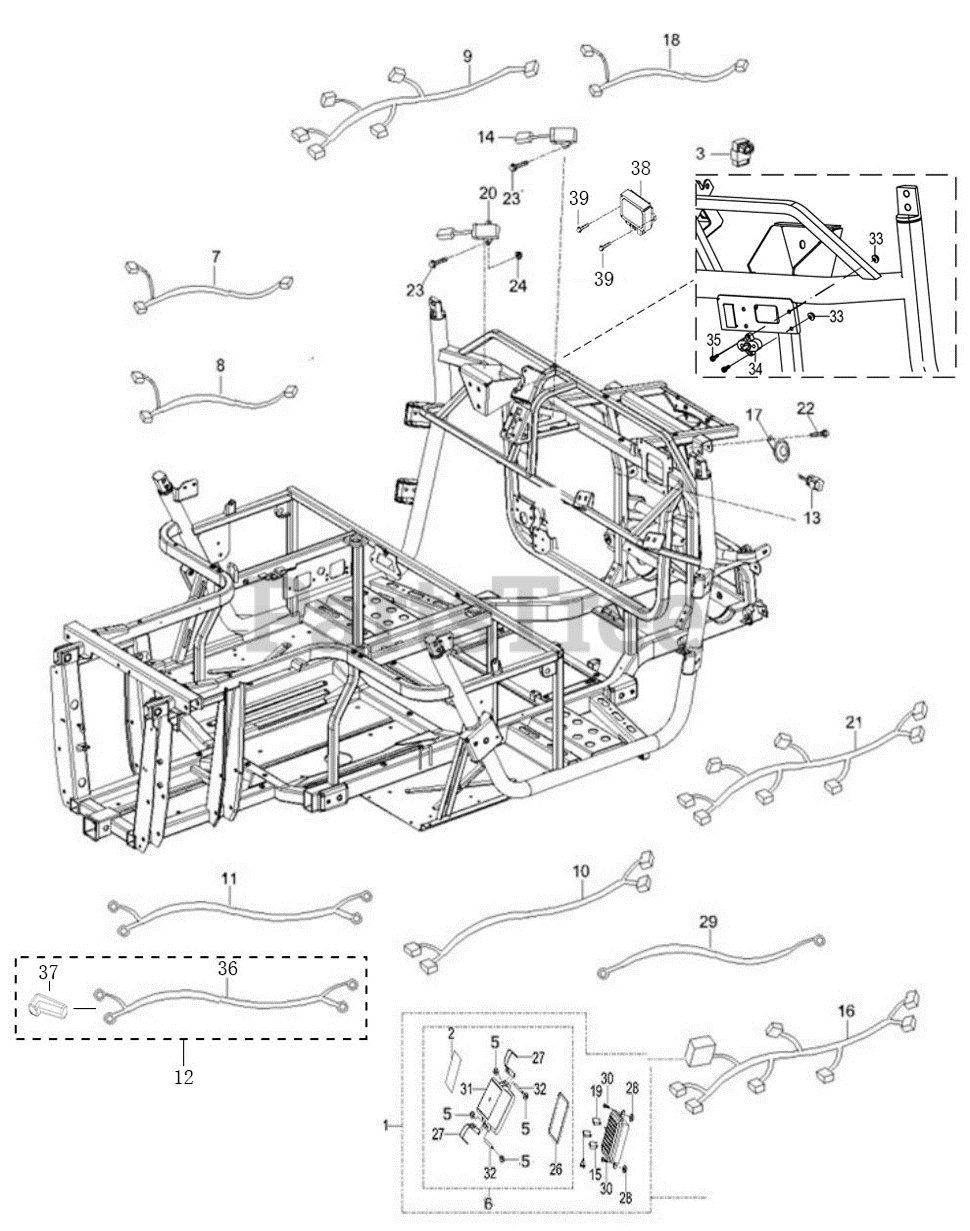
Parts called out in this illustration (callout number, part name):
1	Fuse Box
2	FUSE BOX LABEL
3	RELAY (Rear Diff)
4	SUPPLEMENTARY RELAY
6	FUSE BOX COVER W/ GASKET
7	SWITCH HARNESS
8	CABLE-SWITCH KIT 2
9	GROUND HARNESS
10	VOLTAGE REGULATOR HARNESS
11	CABLE-WINCH RELAY OUTLET
12	WINCH CABLE
13	RADIATOR FAN RELAY
15	CUTOUT RELAY
16	MAIN HARNESS
17	HORN ASSEMBLY
18	BATTERY HARNESS
19	FLASHER RELAY
20	SPEED LIMITER 750 (2018)
20	SPEED LIMITER 550 (2018)
21	HARNESS-750 EFI
22	CROSS PLATE HEAD SCREW M6X12
23	HEXAGON FLANGE BOLT M6X20
24	LOCK NUT M6
25	HEXAGON FLANGE BOLT M6X20
26	FUSE BOX GASKET
27	FUSE BOX CLAMP
28	HEX FLANG NUT M6
29	GROUND HARNESS
30	SOCKET HEX HEAD SCREW M6X20
31	FUSE BOX COVER
33	HEX FLANGE NUT M4
34	Terminal Lug
35	Cross Recessed Head And Spring Washer Assy M4×12
38	EPS CONTROLLER
39	HEXAGON FLANGE BOLT M6X20
